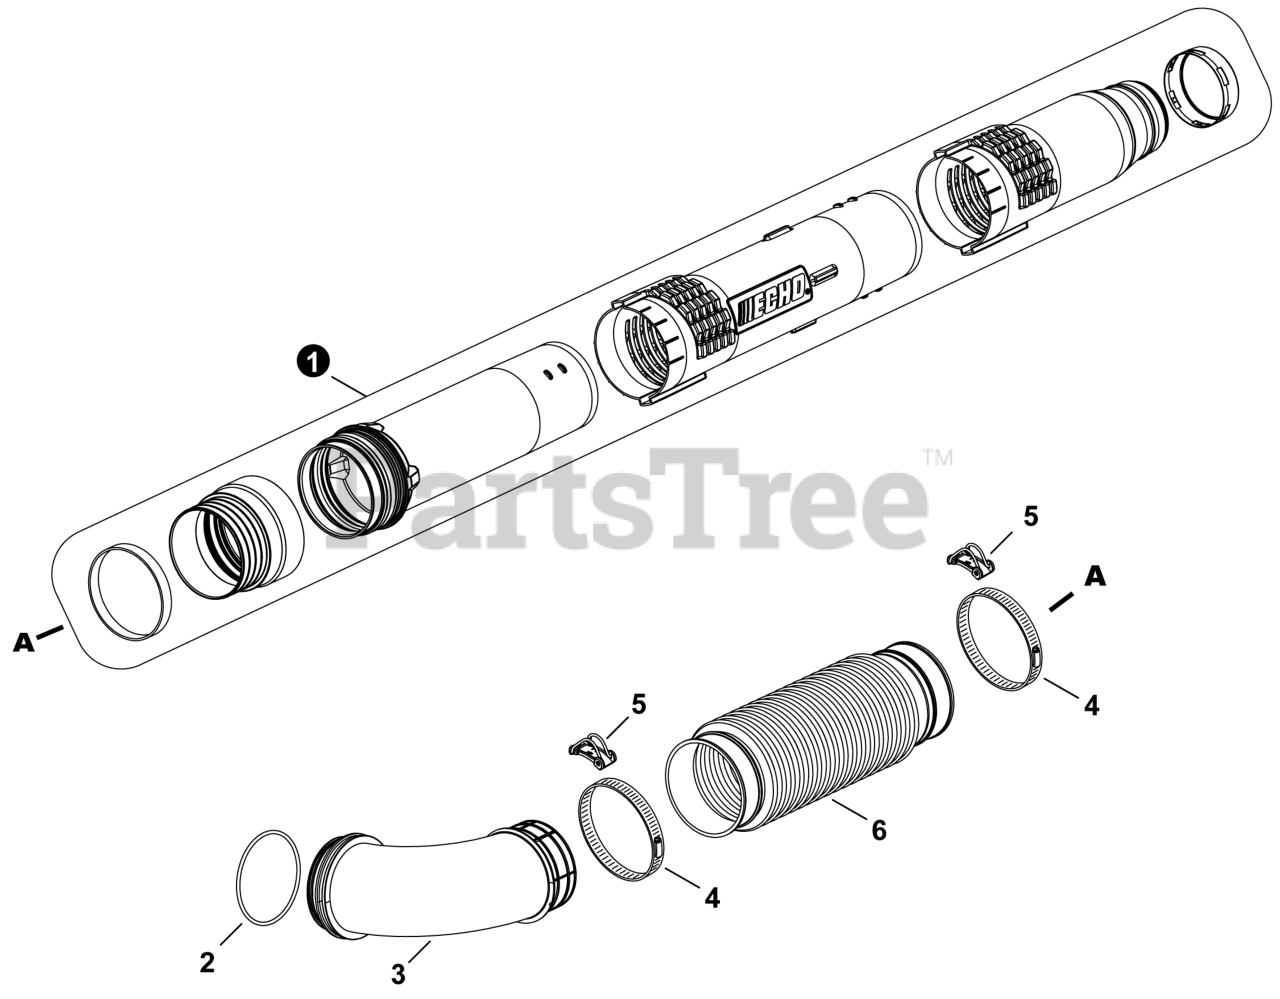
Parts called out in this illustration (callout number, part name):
1	BLOWER TUBE ASSEMBLY
3	TUBE, BLOWER - ELBOW
4	CLAMP, BLOWER TUBE
5	CLIP, CABLE
6	TUBE, BLOWER - FLEXIBLE
